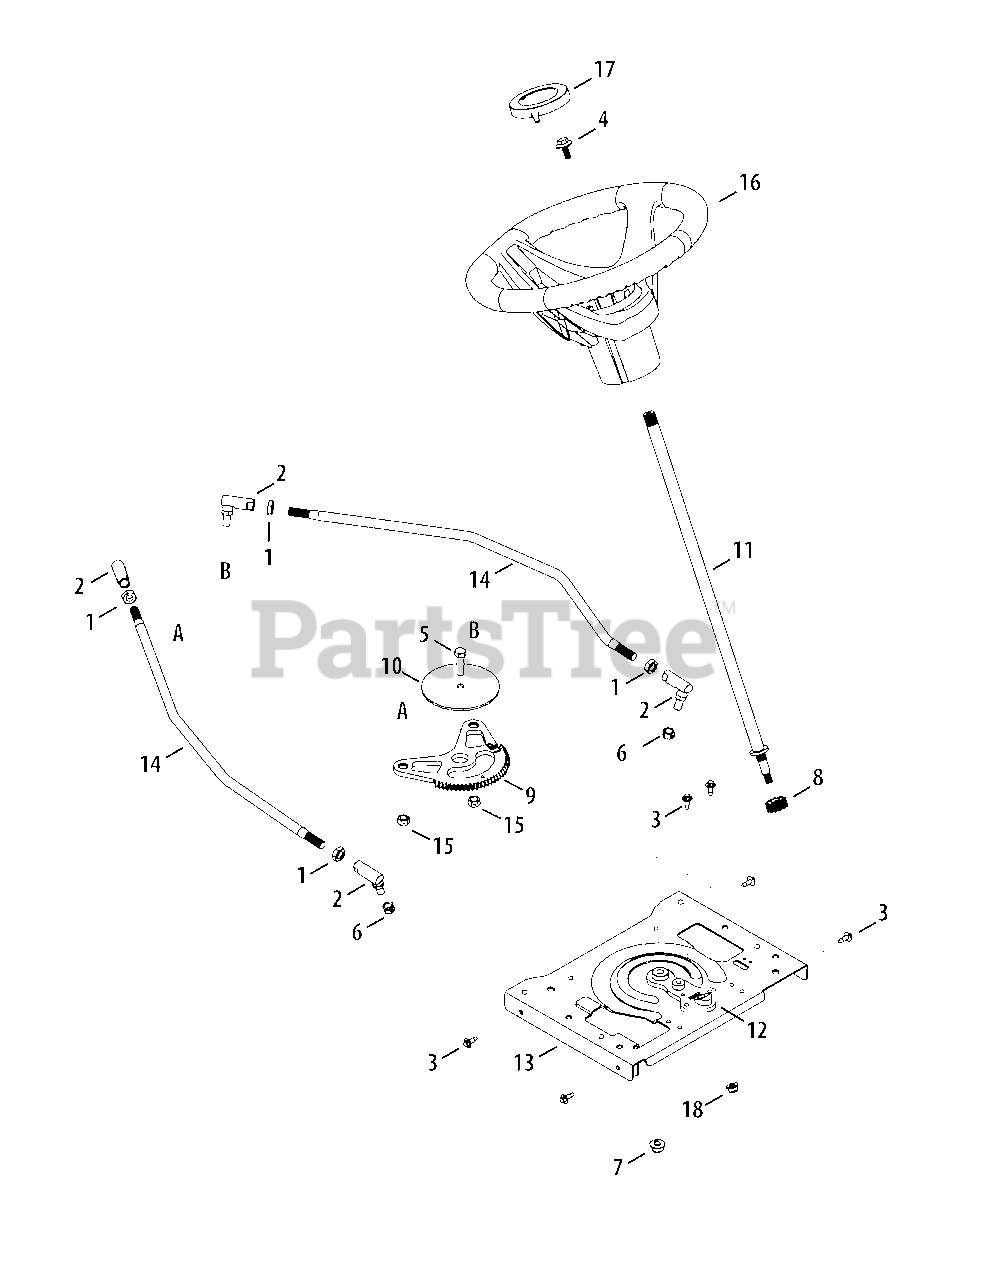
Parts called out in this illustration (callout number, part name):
1	Jam Nut, 1/2-20
2	Ball Joint, 1/2-20, Lock
3	Screw, M6-1 x .625
4	Screw, 5/16-24 x .850
5	Hex Cap Screw, 3/8-16 x 1.25
6	Nut, Hex Lock, 7/16-20
7	Nut, Flange Lock, 3/8-16, Grf,
8	Pinion Gear, 13T
9	Steering Gear
10	Flat Washer, .385 x 4.0 x .120
11	Shaft, Steering, .625 OD x 20
12	Steering Support
13	Steering Mounting Plate
14	Steering Rod Assy (Incl. ref. 1 & 2)
15	Jam Nut, 7/16-20
16	Steering Wheel
17	Cap, Steering Wheel
18	Nut, Flange Lock, 5/16-18, Grf
